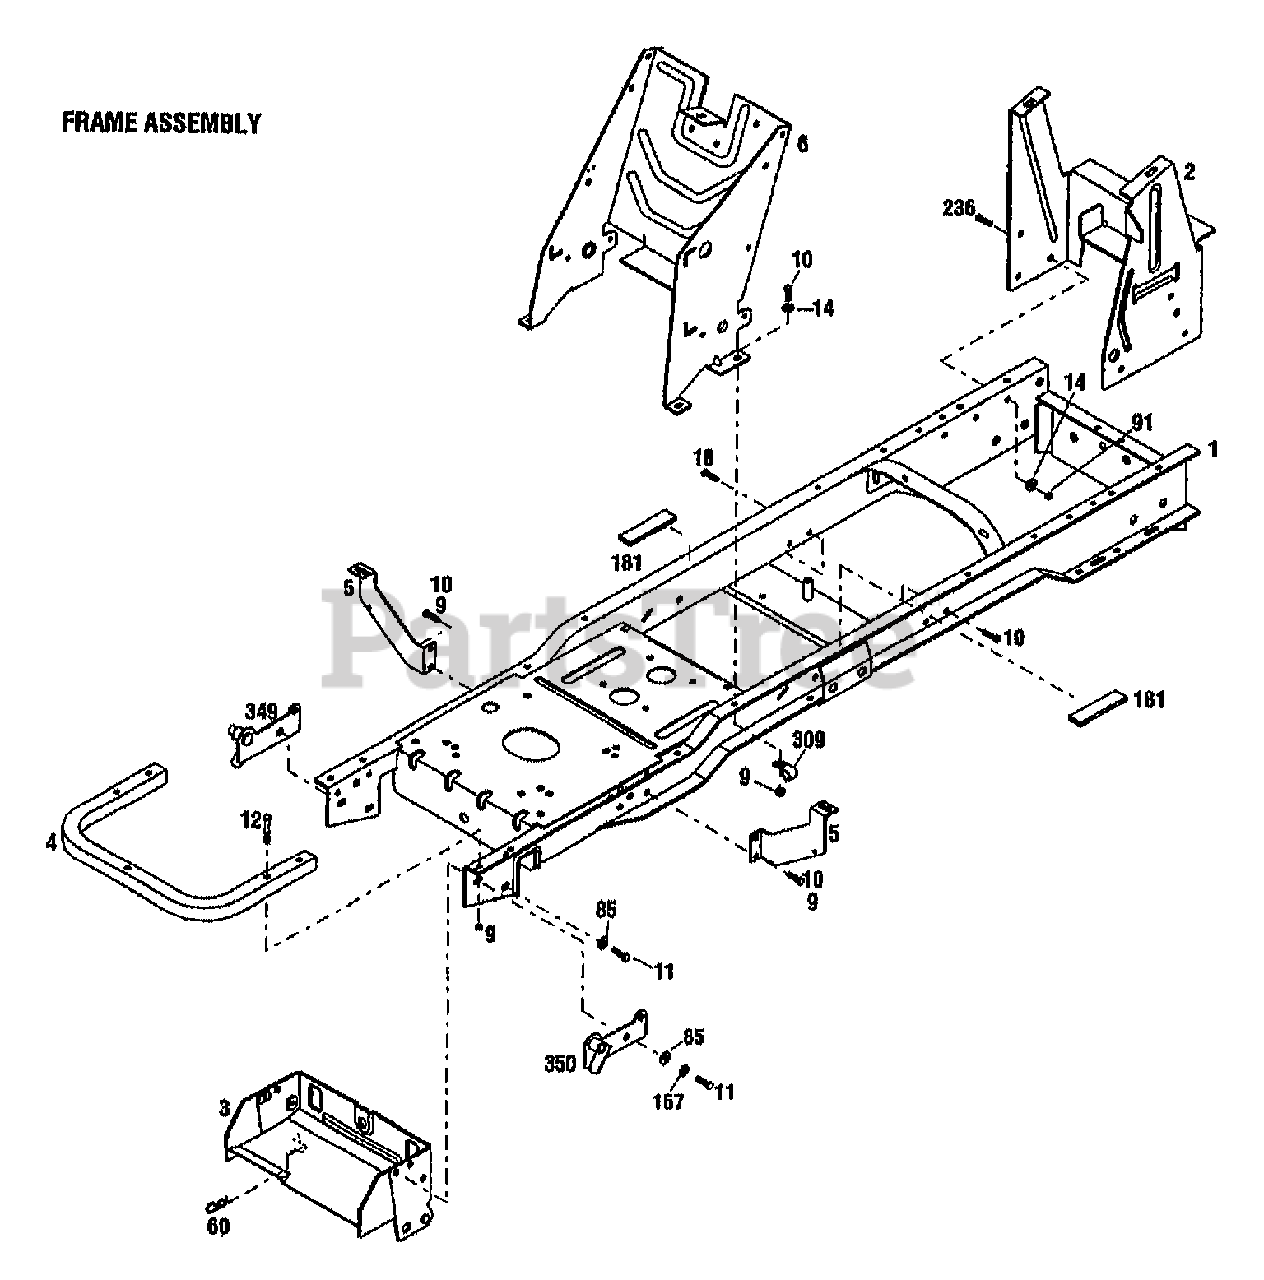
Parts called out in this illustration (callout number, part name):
1	ASSM-FRAME LTX
2	SUPPORT-REAR TANK
3	ASSM-BRKT ATTACHMENT
4	BUMPER-FRONT
5	SUPPORT-FENDER
6	SUPPORT-CONSOLE
9	NUT-HFLK 5/16-18 ZP
10	SCR-HHC 5/16-18X.75 GR 5 ZP
11	SCR-HH 3/8-16X1.0 G5 ZP
12	SCR-HH 5/16-18X1.75
14	WASHER-FLAT 5/16 SAE
60	PIN-HITCH .125X2.56 ZP
85	WASHER-FLAT 3/8 SAE
91	NUT-TOP/LK 5/16-18 ZP
167	WASHER-LK .375 @ DEPL
236	SCR-HFLK 5/16-18X.75 ZP
309	CLIP-J
349	PLATE-PIVOT RH
350	PLATE-PIVOT LH
